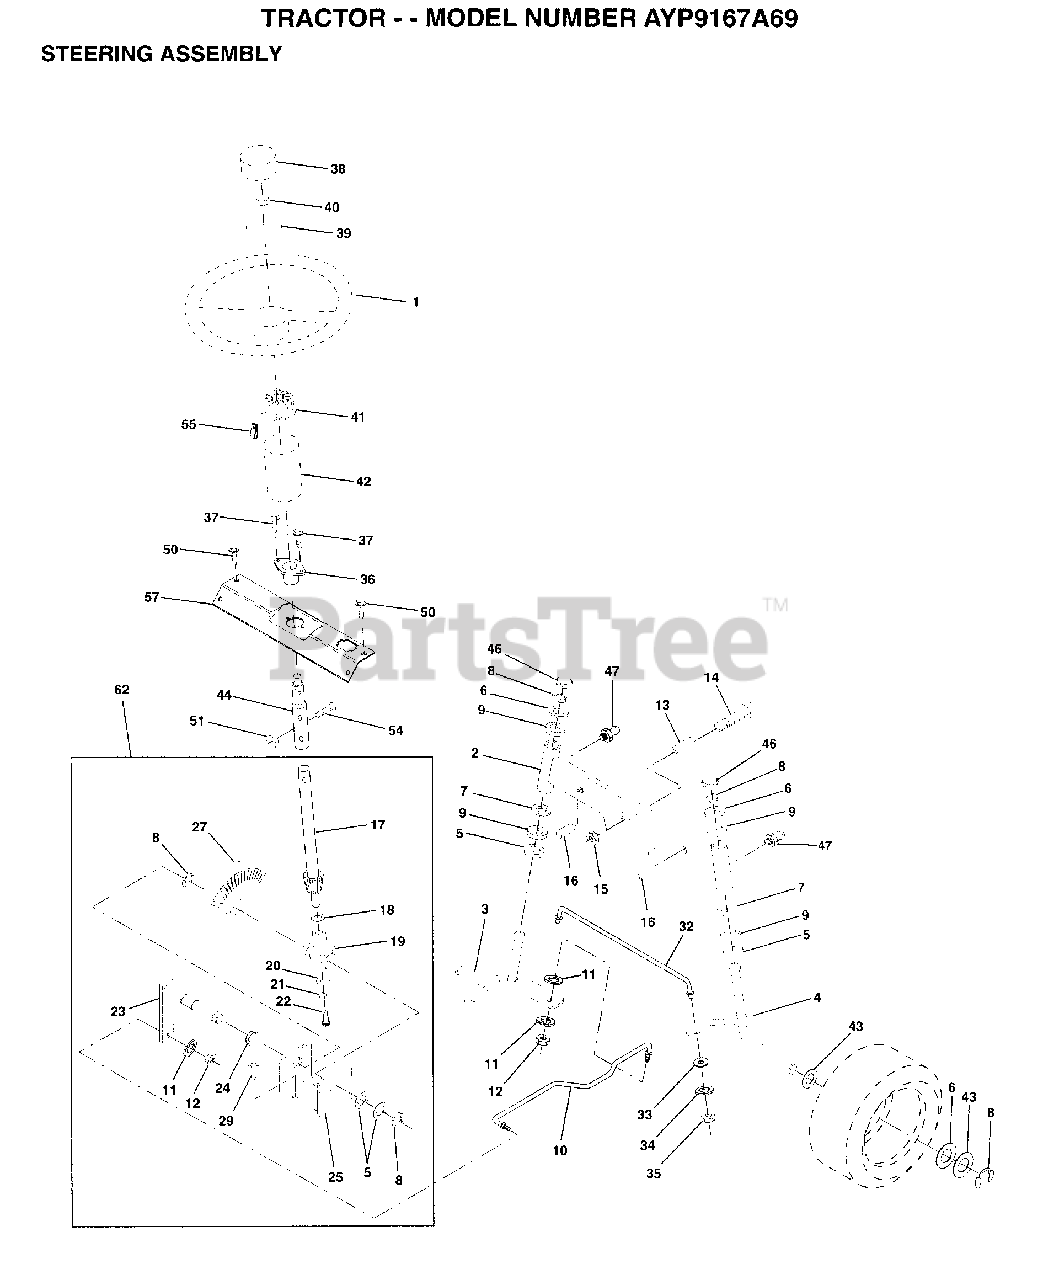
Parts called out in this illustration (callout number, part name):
1	WHEEL STR AYP BLK
2	AXLE ASM FRONT
3	SPINDLE LH
4	SPINDLE RH
5	WASHER .T
6	WASHER
7	WASHER
8	RING
9	COL. SRTG. BEAR.
11	LOCKWASHER
13	BEARING
14	BOLT HEX 5/8-11
15	"NUT-LOC,FLANGE LT"
16	AXLE PIN
17	SHAFT ASM STEERIN
18	THRUST WASHER
19	SUPPORT.SHAFT
21	LOCKWASHER
22	"SCREW,SPECIAL"
24	NYLINER T
25	"BRKT,STEERING"
27	GEAR SECTOR
29	SCREW
32	TIE ROD
33	WASHER M
34	LOCKWASHER
35	NUT.LOCK.5/16-24
38	CAP STEER AYP
39	WASHER T
40	GRIPCO NUT
41	ADAPTER-WHEEL LT
42	BOOT SHAFT STEER
43	WASHER
46	CAP
47	ZERK M
50	SCREW HEX CRT
51	NUT
54	BOLT
55	CLIP TINNERMAN
57	SUPPORT SHAFT STR
